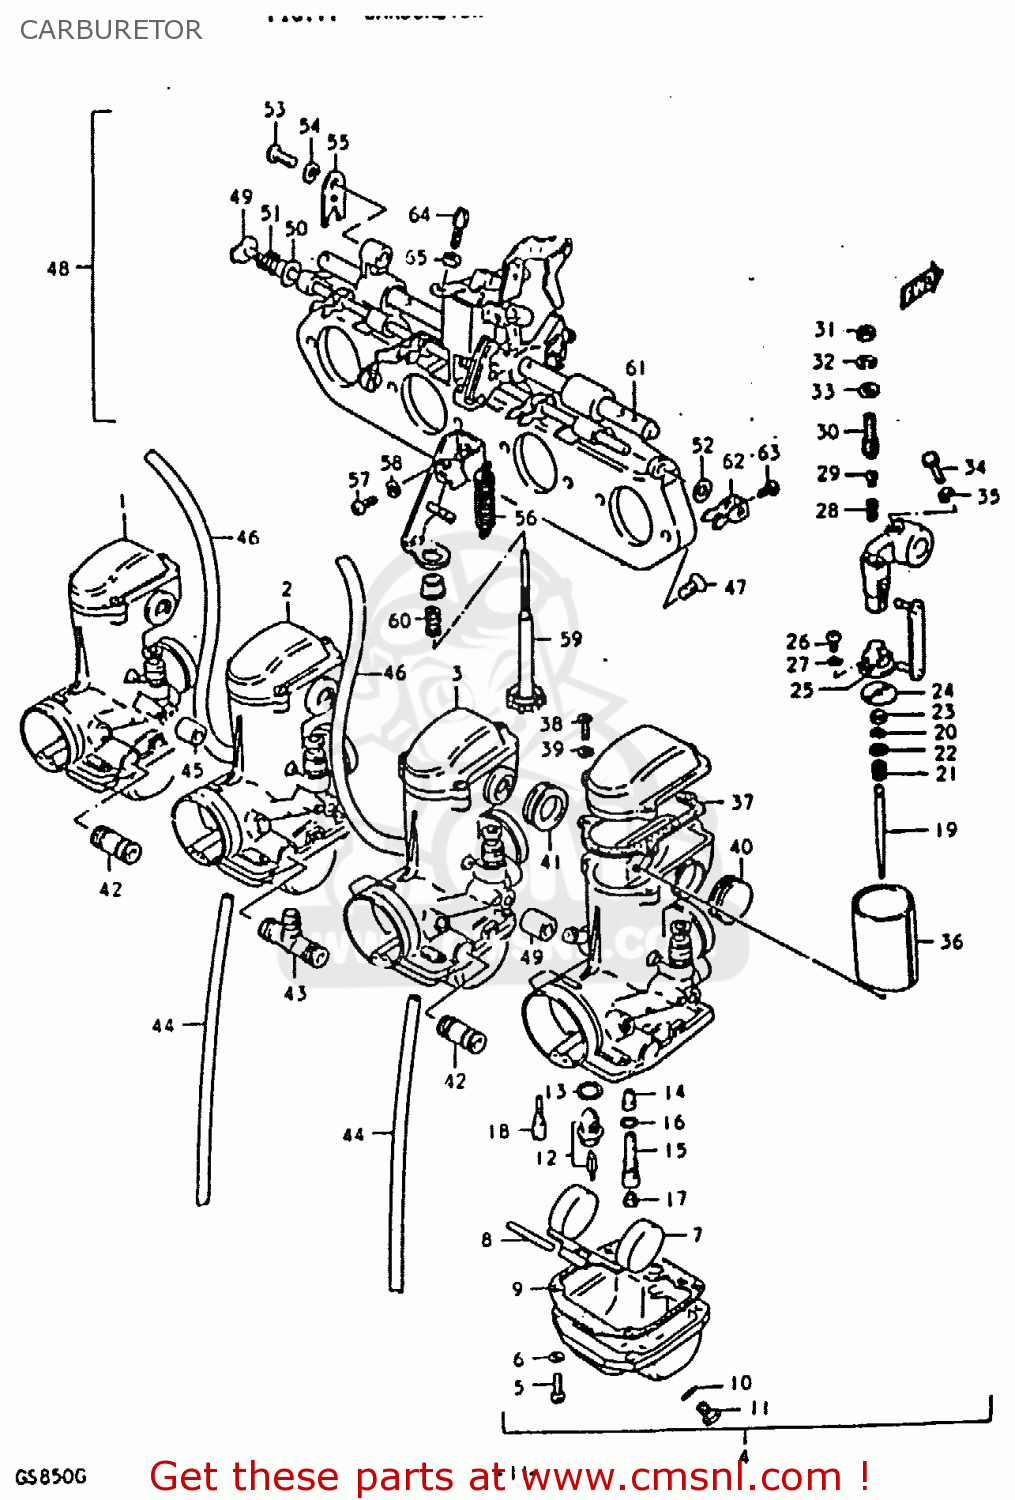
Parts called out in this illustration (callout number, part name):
1	CARBURETOR ASSY, NO. 1
2	CARBURETOR ASSY, NO. 2
3	CARBURETOR ASSY, NO. 3
4	CARBURETOR ASSY, NO. 4
5	SCREW
6	LOCK WASHER
7	FLOAT
8	PIN,FLOAT
9	GASKET,FLOAT CHAMBER (NAS)
10	O RING
11	SCREW
12	VALVE ASSEMBLY,NEEDLE
13	GASKET,VALVE SEAT (NAS)
14	JET,NEEDLE
15	PIPE,BLEEDER
16	O RING
17	JET
18	JET
19	NEEDLE,JET
20	CLIP
21	SPRING
22	WASHER,JET NEEDLE
23	RING
24	PLATE,THROTTLE VALVE
25	CONNECTOR
26	SCREW
27	LOCK WASHER
28	SPRING
29	PIN,CARBURETOR
30	SCREW
31	NUT
32	LOCK WASHER
33	WASHER
34	BOLT
35	LOCK WASHER
36	VALVE,THROTTLE
37	GASKET (NAS)
38	SCREW
39	LOCK WASHER
40	PIPE,DELIVERY
41	SEAL
42	NIPPLE
43	NIPPLE
44	HOSE
45	HOSE
46	HOSE 4.5X8X390
47	SCREW
48	CARBURETOR ASSEMBLY
49	SHAFT,STARTER
50	WASHER
51	SPRING
52	WASHER,STARTER SHAFT
54	LOCK WASHER
55	GASKET
56	SPRING,THROTTLE RETURN
57	SCREW
58	LOCK WASHER
59	ADJUSTER
60	SPRING,THROTTLE SCREW
61	SHAFT ASSEMBLY
62	LEVER,STARTER
63	SCREW
64	ADJUSTER,CABLE
65	NUT
66	JET
